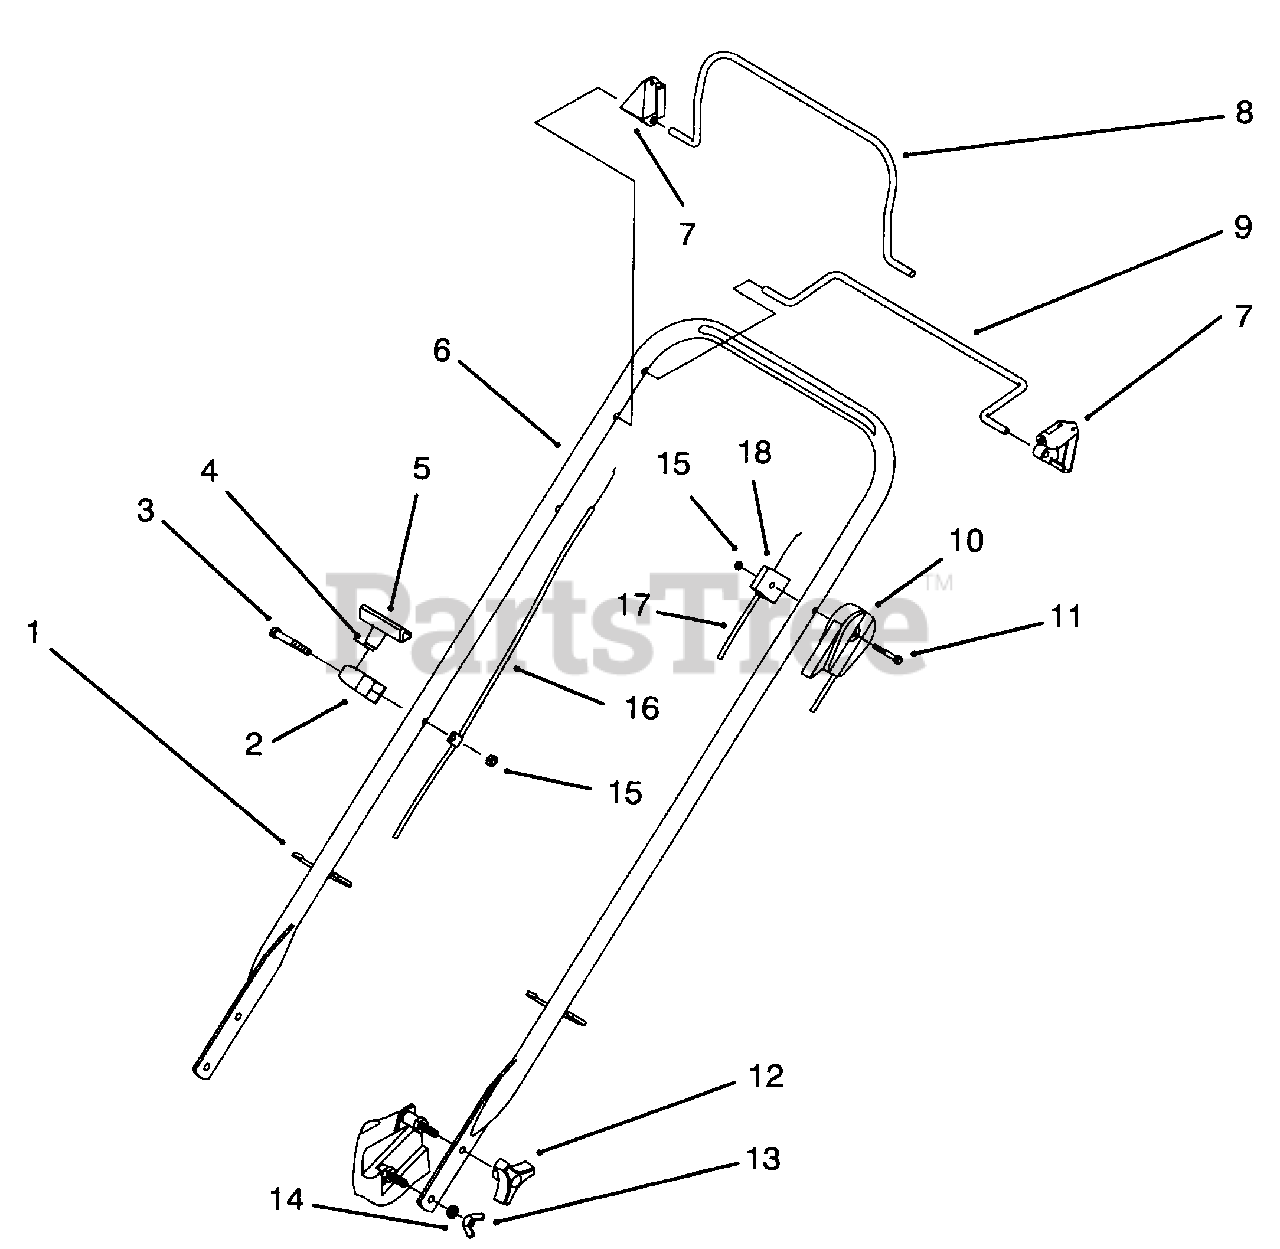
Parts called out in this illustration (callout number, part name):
1	Tie-Cable
2	Guide-Rope
3	Screw-Hex Hd. Cap
4	Handle-Starter
5	Clip-Rope Insert
7	Stop-Pivot
8	Bail-Flywheel Brake
9	Bail-S.P. Control
10	Cable-Throttle
11	Screw-Hex Hd. Cap
12	Knob
14	Washer-Lock
15	Nut-Lock Insert
16	Cable-Brake
17	Cable-Traction
18	Anchor-Cable S.P. Upper
